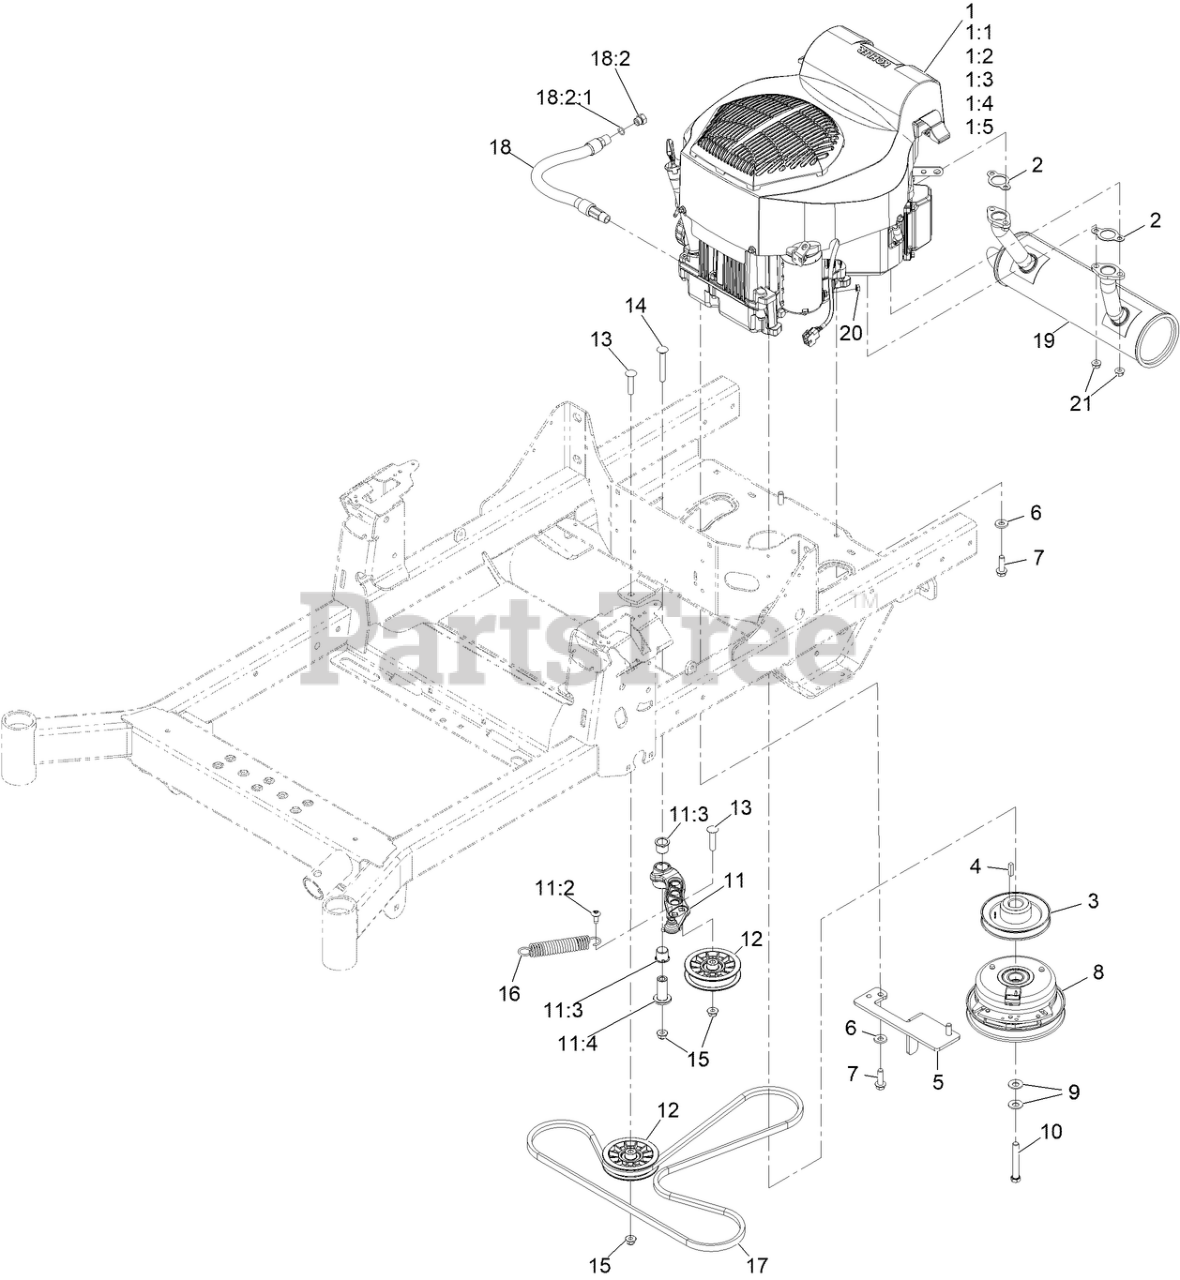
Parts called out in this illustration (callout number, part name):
1:1	ELEMENT-PRE CLEANER
1:2	ELEMENT-AIR FILTER
1:3	Filter-Oil
1:4	Filter-Fuel
1:5	Plug-Spark
2	GASKET (KOHLER)
3	SHEAVE, ENGINE
5	Anchor-Clutch
6	WASHER-BELLEVILLE
7	SCREW-THD
8	CLUTCH 1.00
9	WASHER-SPRING
10	SCREW-HH W/LOCTITE
11	ASM, PUMP IDLER
11:2	SCREW, TAPTITE
11:3	BUSHING, IGUS
11:4	Spacer, Idler Pivot
12	PULLEY-FLAT IDLER
13	SCREW-CARR
14	SCREW-CARR
15	NUT-HF, NI
16	SPRING-EXTENSION
17	BELT-V
18	OIL DRAIN HOSE ASM
18:2	PLUG-HH
18:2:1	O-RING
19	MUFFLER, KOHLER
21	NUT-FLANGE
